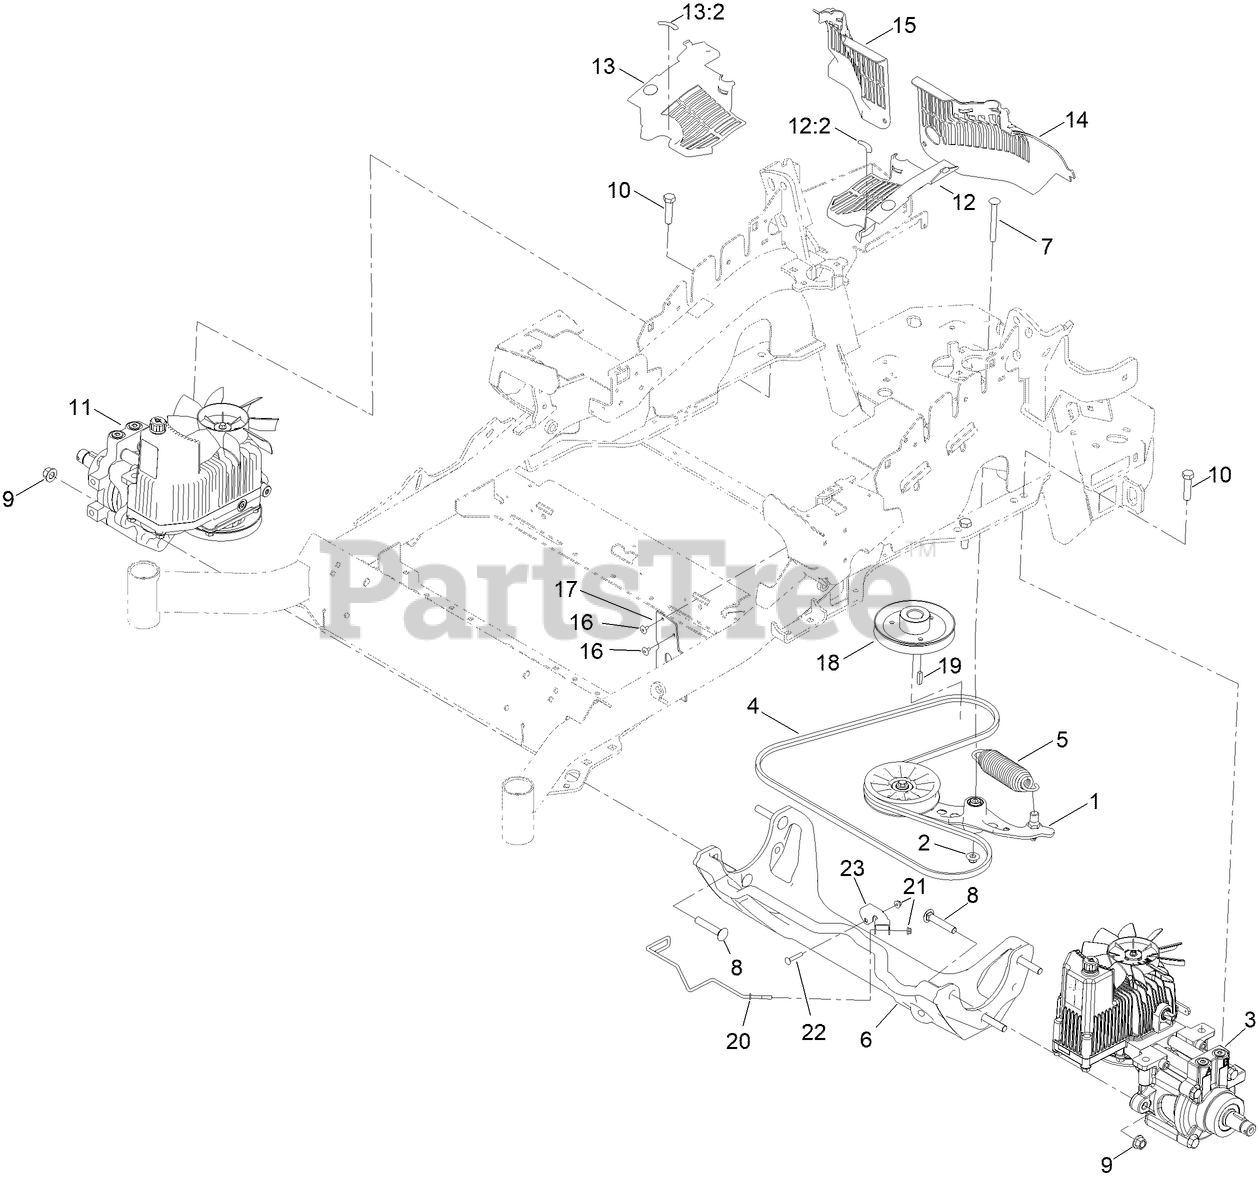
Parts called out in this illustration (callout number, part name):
1	PUMP IDLER ASM
2	NUT-FLANGE, NI
3	HYDRO-LH
4	BELT-V
5	SPRING-EXTENSION
6	CRADLE-HYDRO
7	BOLT-SHOULDER, CARRIAGE
8	SCREW-CARR
9	NUT-LOCK
10	SCREW-HH
11	HYDRO-RH
12	LH HYDRO GUARD ASM
12:2	DECAL-OIL, HYDRO
13	RH HYDRO GUARD ASM
13:2	DECAL-OIL, HYDRO
14	GUARD-HYDRO, REAR (LH)
15	GUARD-HYDRO, REAR (RH)
16	RIVET-POP
17	DEFLECTOR-AIR FLOW
18	SHEAVE, W/HUB
20	GUIDE-BELT
21	NUT-HF
22	SCREW-CARR
23	BRACKET-U
